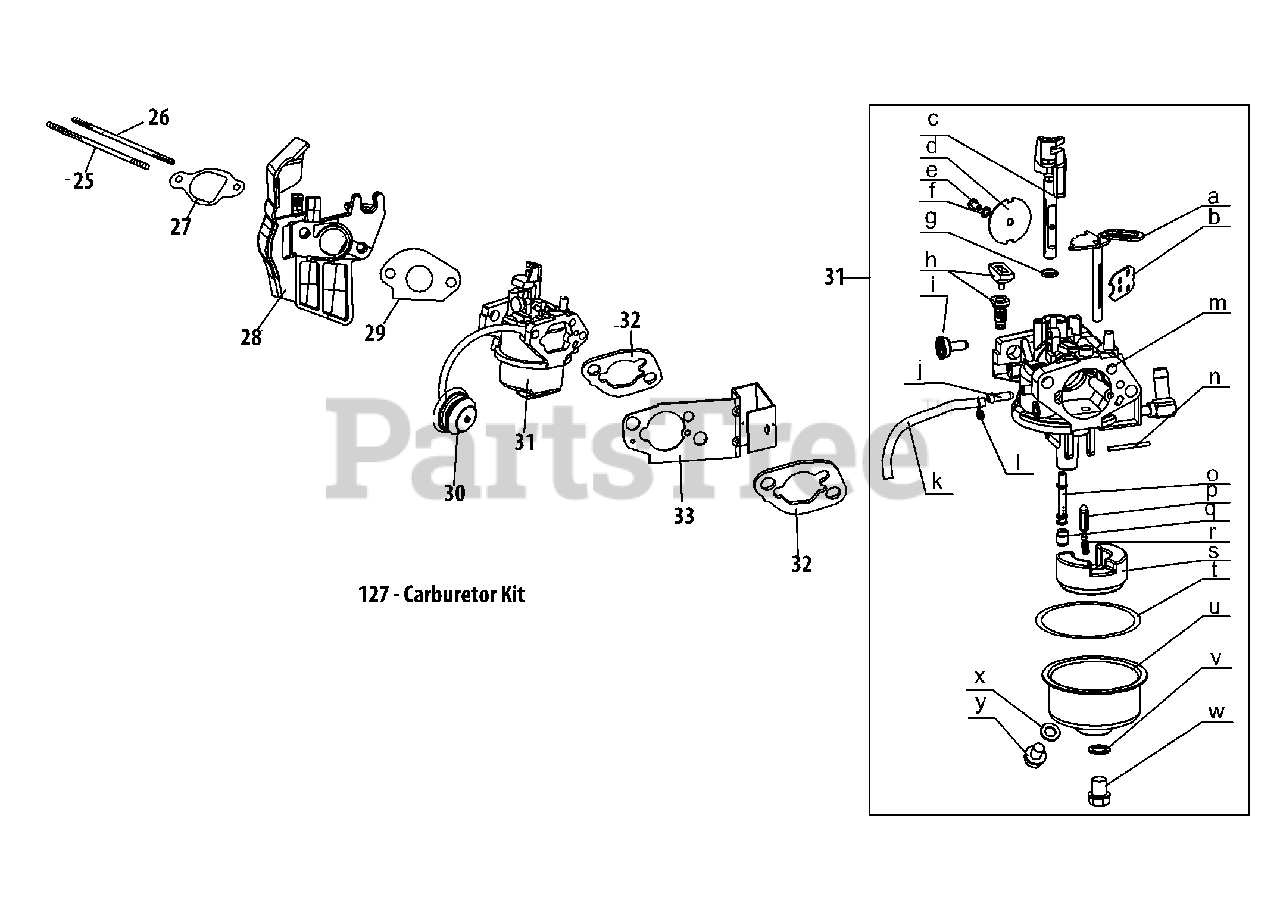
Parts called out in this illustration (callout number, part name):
25	Stud M6×117
26	Stud M6×105
27	Carburetor Insulator Gasket
28	Carburetor Insulator
29	Carburetor Gasket
30	Primer Assembly
30	Primer Bulb
31	Carburetor Assembly (Hy-170Sa)
31	Carburetor Assembly (Dn-170Sa)
32	Carburetor Gasket Plate
33	Choke Control
127	Carburetor Kit - Huayi
127	Carburetor Kit - Deni
